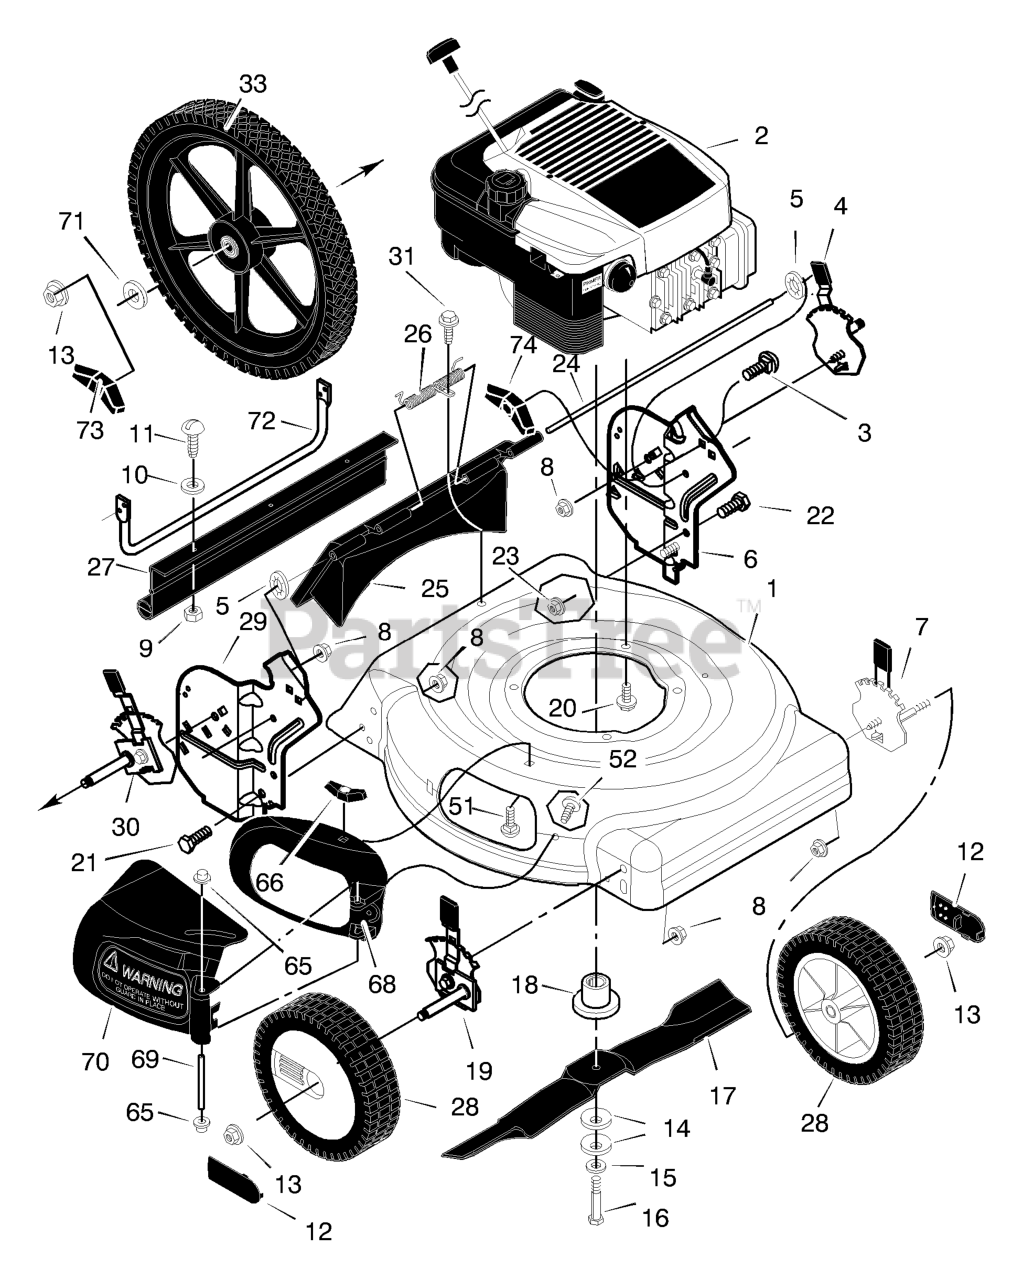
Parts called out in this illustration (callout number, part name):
1	Housing
2	Engine *
3	Bolt, Carriage
4	Adjuster, Left Rear Height
5	Push On Cap
6	Bracket, Left Handle
7	Adjuster, Left Front Height
8	Nut, Flange
9	Nut, Hex
11	Screw
12	Cap, Hub
13	Nut, Flange
14	Washer, Belleville
18	Adapter, Blade
19	Adjuster, Right Front Height
20	Bolt, Engine
21	Bolt
22	Bolt
23	Nut, Flange
24	Rod, Pivot
25	Door, Rear (Black)
27	Guard, Rear
28	Wheel & Tire, Front
29	Bracket, Right Handle
30	Adjuster, Right Rear Height
33	Wheel & Tire, Rear
51	Bolt, Carriage
65	Push On Cap
66	Wingnut
68	Bezel (Black)
69	Pin, Pivot
70	Deflector, Chute (Black)
